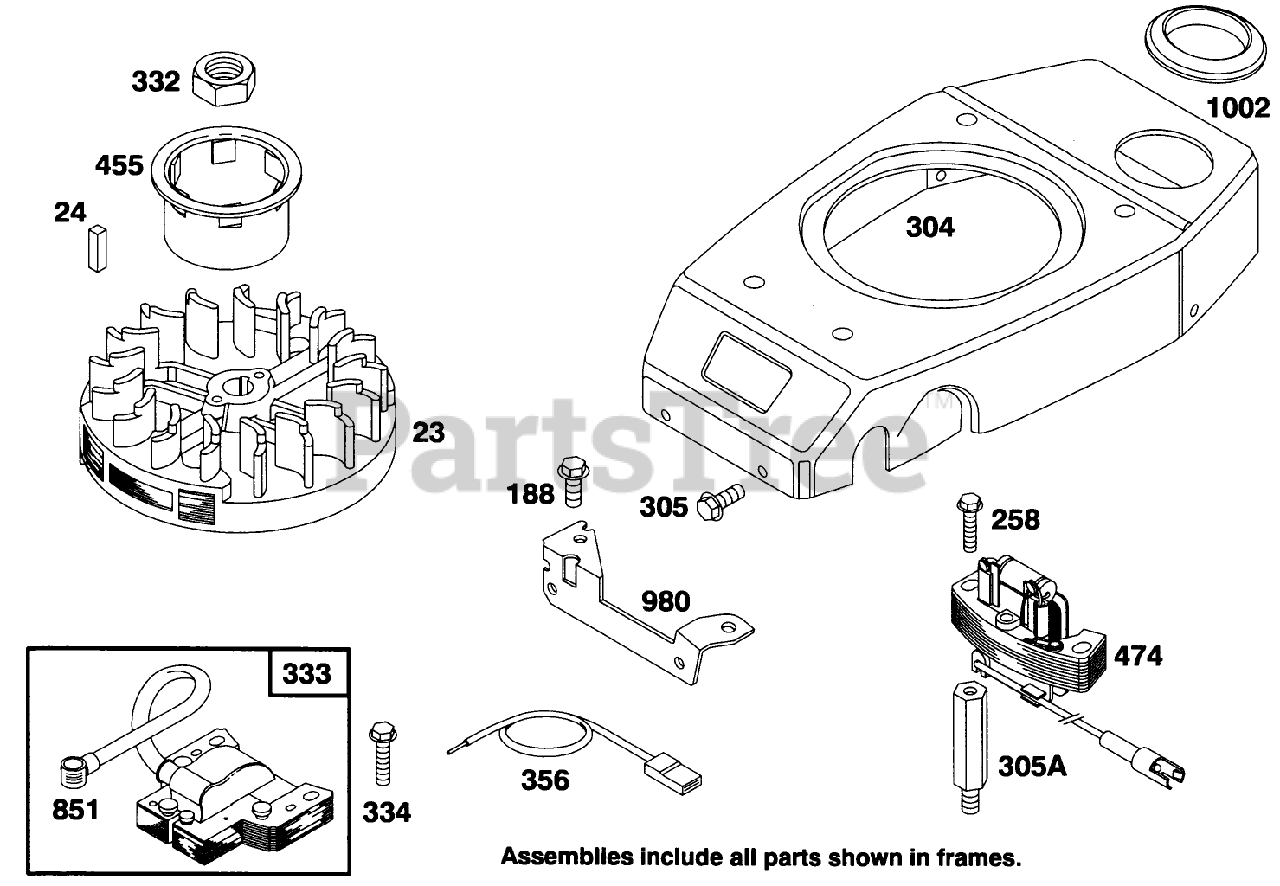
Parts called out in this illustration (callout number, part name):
24	KEY - FLYWHEEL
304	HOUSING - BLOWER
305	SCREW - HEX HEAD
332	NUT - HEXAGON
356	WIRE - GROUND
980	BRACKET-BLOWER HSG
